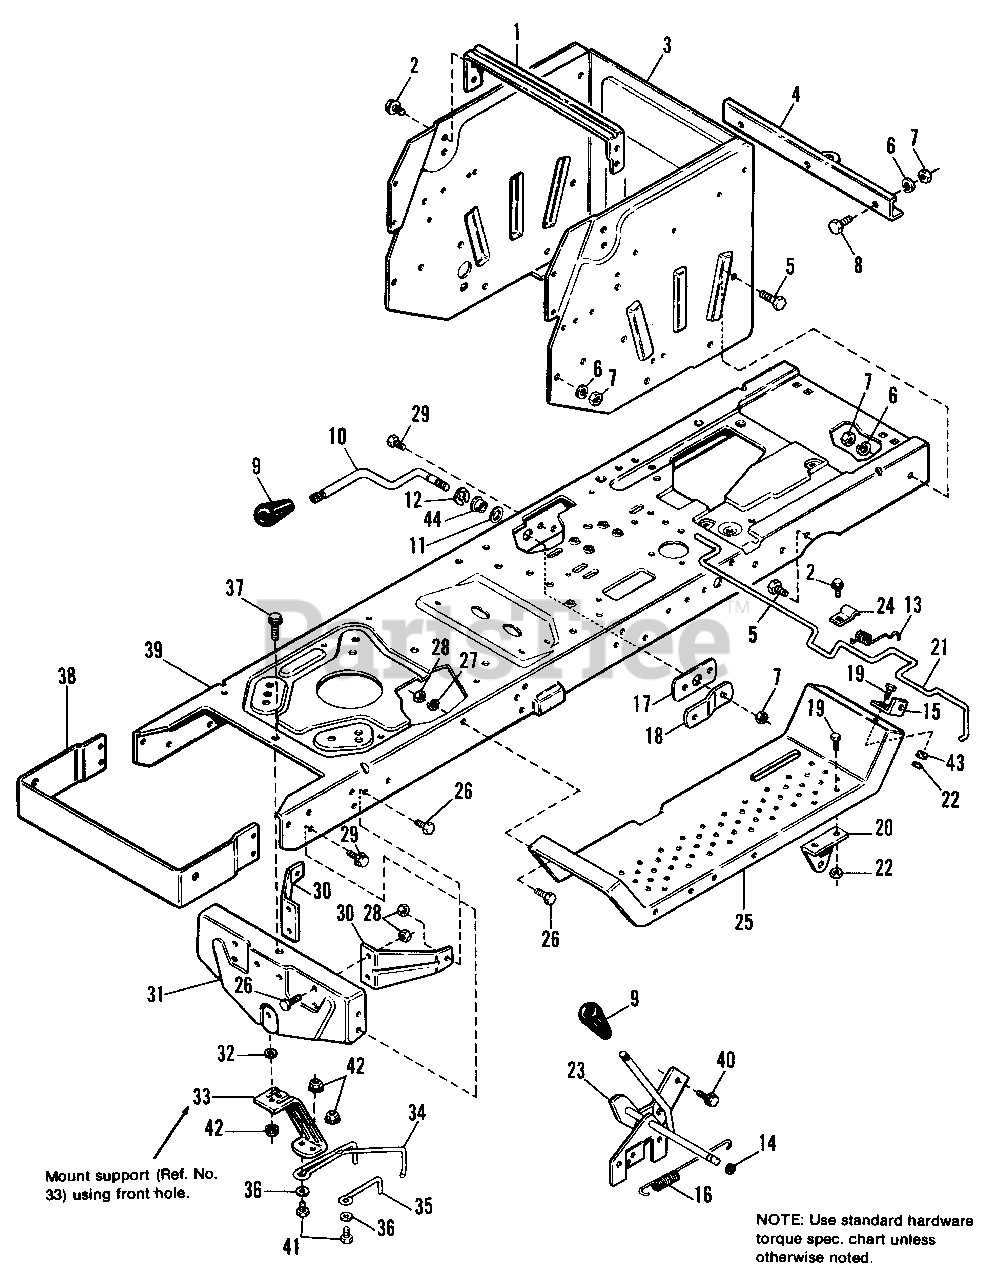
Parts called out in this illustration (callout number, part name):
1	BRACE, Seat
2	SCREW, Taptite, 5/16-18 x 1/2
3	SUPPORT, Axle Wrapper
4	BAR, Draw
5	CAPSCREW, Hex, 3/8-16 x 1
6	LOCKWASHER 3/8
7	NUT, Hex, 3/8-16
8	CAPSCREW, Hex, 3/8-16 x 3/4
9	KNOB, Handle
10	HANDLE, Lift
12	KLIPRING,1/2
13	SPRING, Torsion
14	RING, Retaining
15	BRACKET, Seat Latch
16	SPRING, Extension
17	BAR, Support
18	ARM, Support
19	CAPSCREW, Hex, 1/4-20 x 5/8
20	SUPPORT, Clutch
21	ROD, Latch
22	NUT, Hex, 1/4-20
23	HANDLE ASSY., PTO Clutch
26	CAPSCREW, Hex, 5/16-18 x 3/4
27	LOCKWASHER, 5/16
28	NUT, Hex, Full, 5/16-18 (Qty. 18 on 8 HP)
29	SCREW, Taptite, 5/16-18 x 3/4
30	BRACE, Axle Support
31	SUPPORT, Axle
32	WASHER, Plain, 11/32-1 x 10 Ga.
36	WASHER, 11/32
37	CAPSCREW, Hex Flange Hd., 5/16-18 x 1-1/4
40	SCREW, Taptite, 1/4-20 x 1/2
41	CAPSCREW, Hex, 5/16-18 x 7/8
42	LOCKNUT, Hex, Flange Whiz, 5/16-18
43	WASHER
